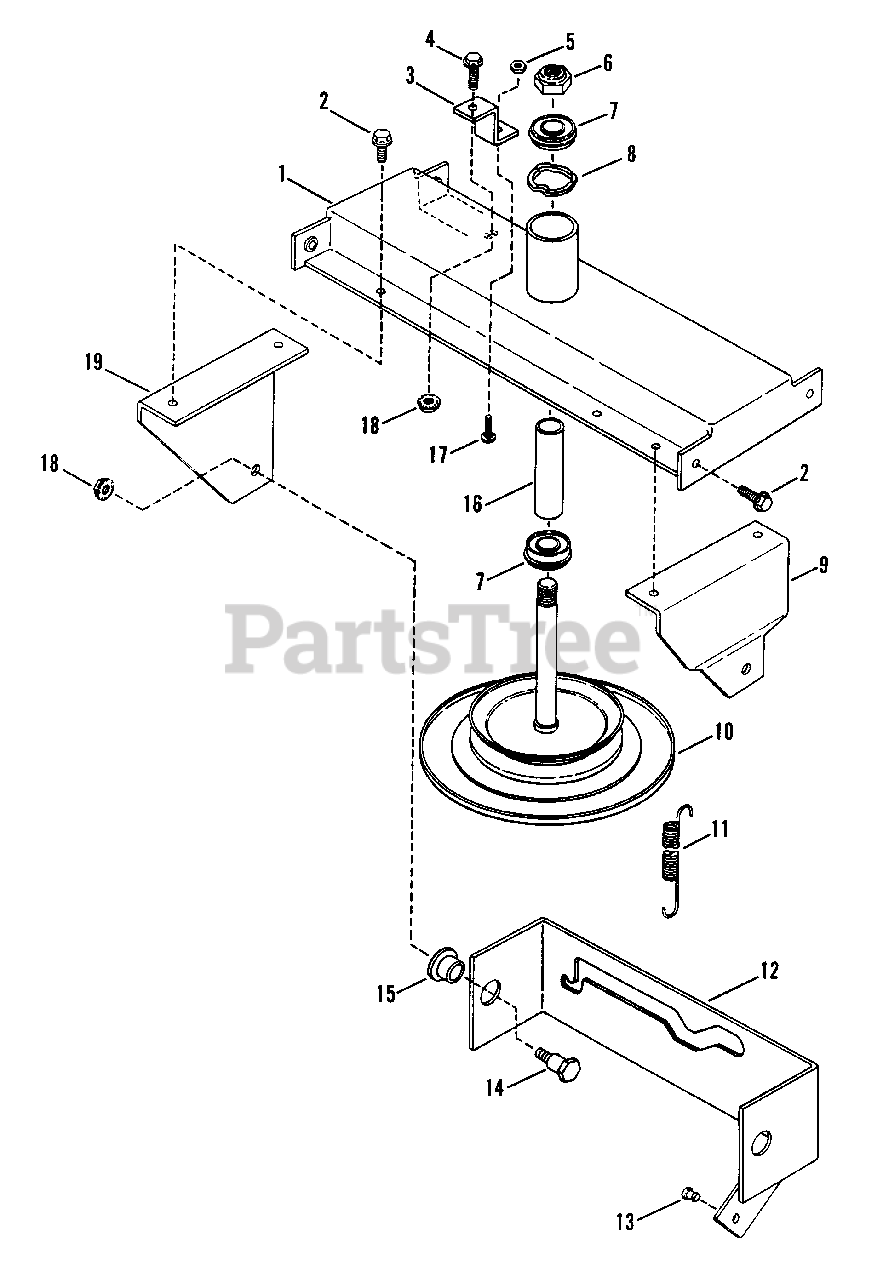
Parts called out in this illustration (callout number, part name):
1	SUPPORT ASSEMBLY, Disc Drive
2	SCREW, 5/16-18 x 1/2' Self-Tapping
3	YOKE STOP ASSEMBLY
4	BOLT, 5/16-18 x 3/4" Hex Flange Lock
5	JAM-NUT, 5/16-18 Hex
6	NUT, 5/8-18 Hex Lock
7	BEARING
8	WASHER, Wave
9	BRACKET, Yoke Pivot, L.H.
10	DISC-DRIVE ASSEMBLY
11	SPRING
12	YOKE, Clutch
13	BEARING, Nyliner
14	BOLT, 5/16-18 x 1 5/16", Shoulder
15	BEARING, Yoke
17	BOLT, 5/16-18 x 1 1/2" Carriage
18	NUT, 5/16-18 Hex Flange Lock
19	BRACKET, Yoke Pivot, R.H.
